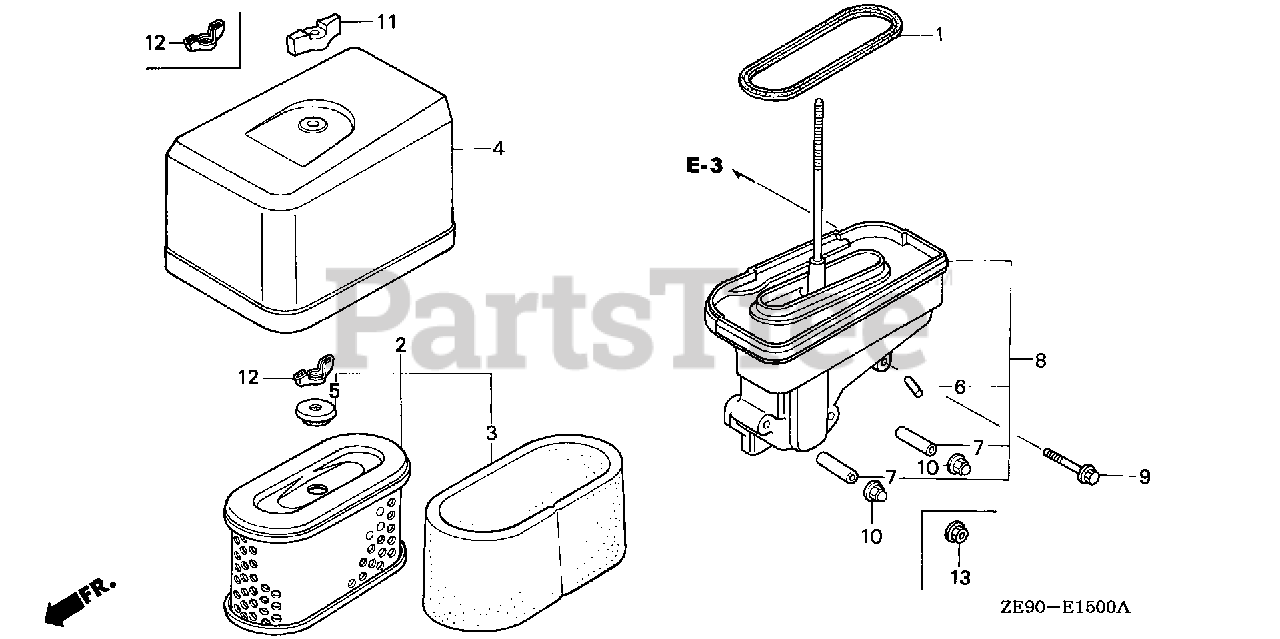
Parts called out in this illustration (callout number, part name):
1	GASKET, ELBOW
2	ELEMENT, AIR CLEANER (METAL BASE)
3	FILTER (OUTER)
4	COVER, AIR CLEANER (DUAL)
5	GROMMET, AIR CLEANER
6	COLLAR, AIR CLEANER
7	COLLAR, AIR CLEANER
8	ELBOW, AIR CLEANER
9	BOLT, FLANGE (6X35) (CT200)
10	NUT, CAP (6MM)
11	WINGNUT
12	NUT, TOOL BOX SETTING
